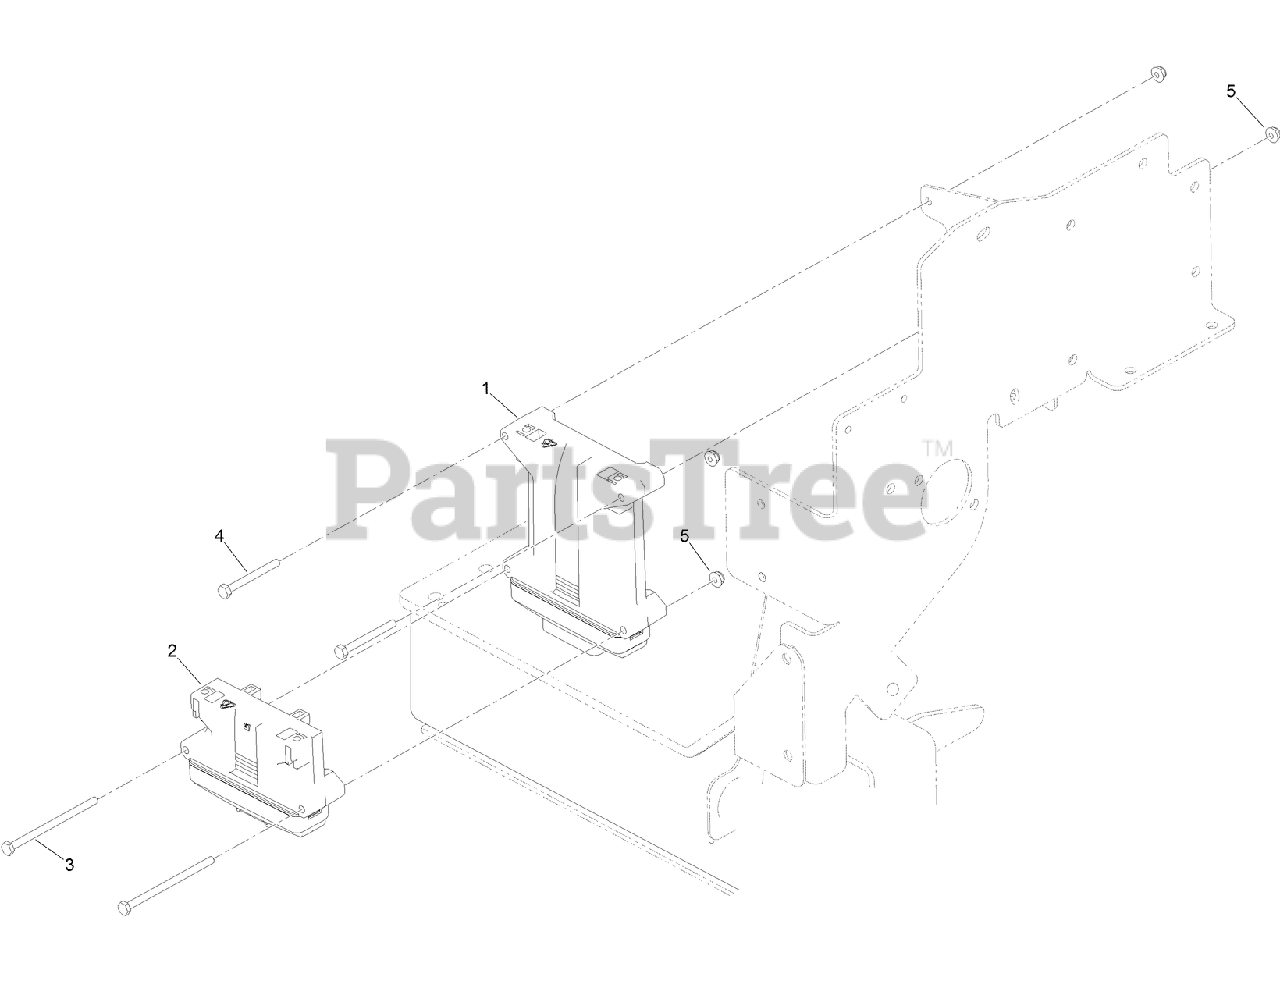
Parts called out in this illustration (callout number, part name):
1	MODULE-CONTROL
2	MODULE-EXPANSION, OUTPUT
3	SCREW-HH
4	SCREW-HH
5	NUT-HF
